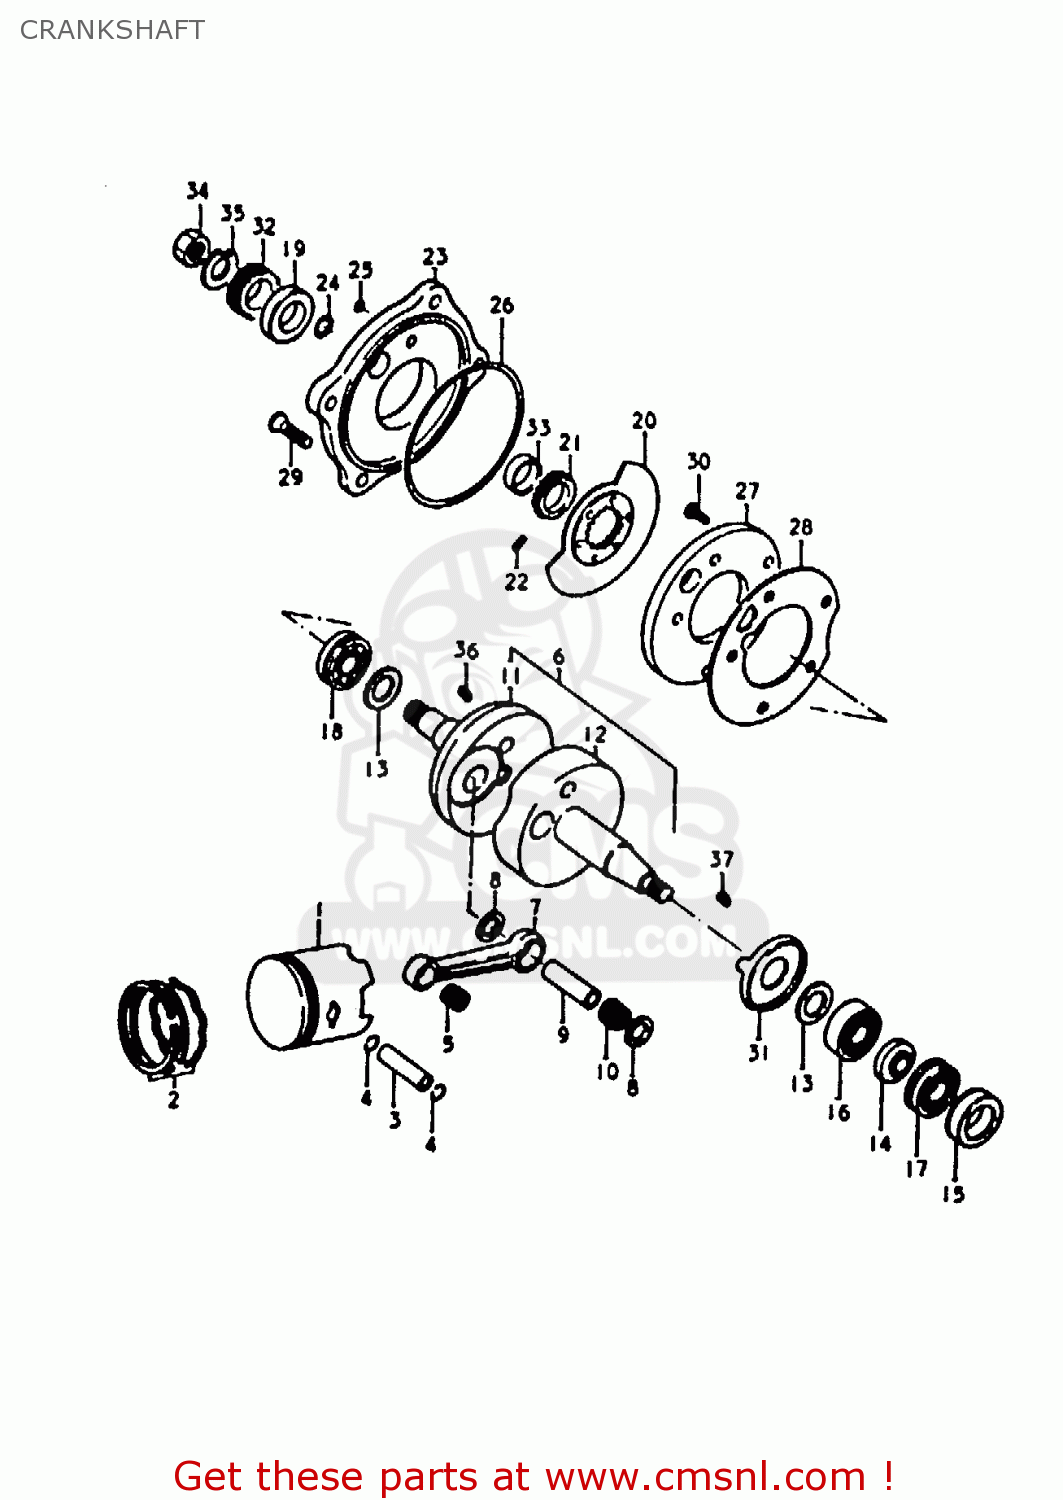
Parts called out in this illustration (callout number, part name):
1	PISTON
2	RING SET,PISTON
3	PIN,PISTON 14MM
4	RING,SNAP 14MM
5	BEARING
6	CRANKSHAFT ASSEMBLY
7	CONNECTING ROD
8	WASHER(19X32X1)
9	PIN,CRANK
10	BEARING
11	CRANKSHAFT, RH
12	CRANKSHAFT,LEFT
13	THRUST WASHER
14	SPACER
15	OIL SEAL
16	BEARING
17	Bearing
18	BEARING(20X52X15)
19	OIL SEAL (25X44X7)
20	VALVE,ROTARY
21	GUIDE,ROTERY VALVE
22	PIN 3X5
23	SEAT,CRANKCASE OUTER VALVE
24	O RING(D:1.5,ID:22.5)
25	O-RING (D:1.5 ID:10)
26	O RING(D:2,ID:99)
27	SEAT,ROTERY VALVE INNER
28	GASKET,ROTERY VALVE INNER SEAT (NAS)
29	SCREW
30	SCREW
31	PLATE,CSHAFT OIL GUIDE
32	GEAR,PRIMARY DRIVE
33	SPACER(20X25X10)
34	NUT
35	WASHER
36	KEY 4MM
37	KEY
